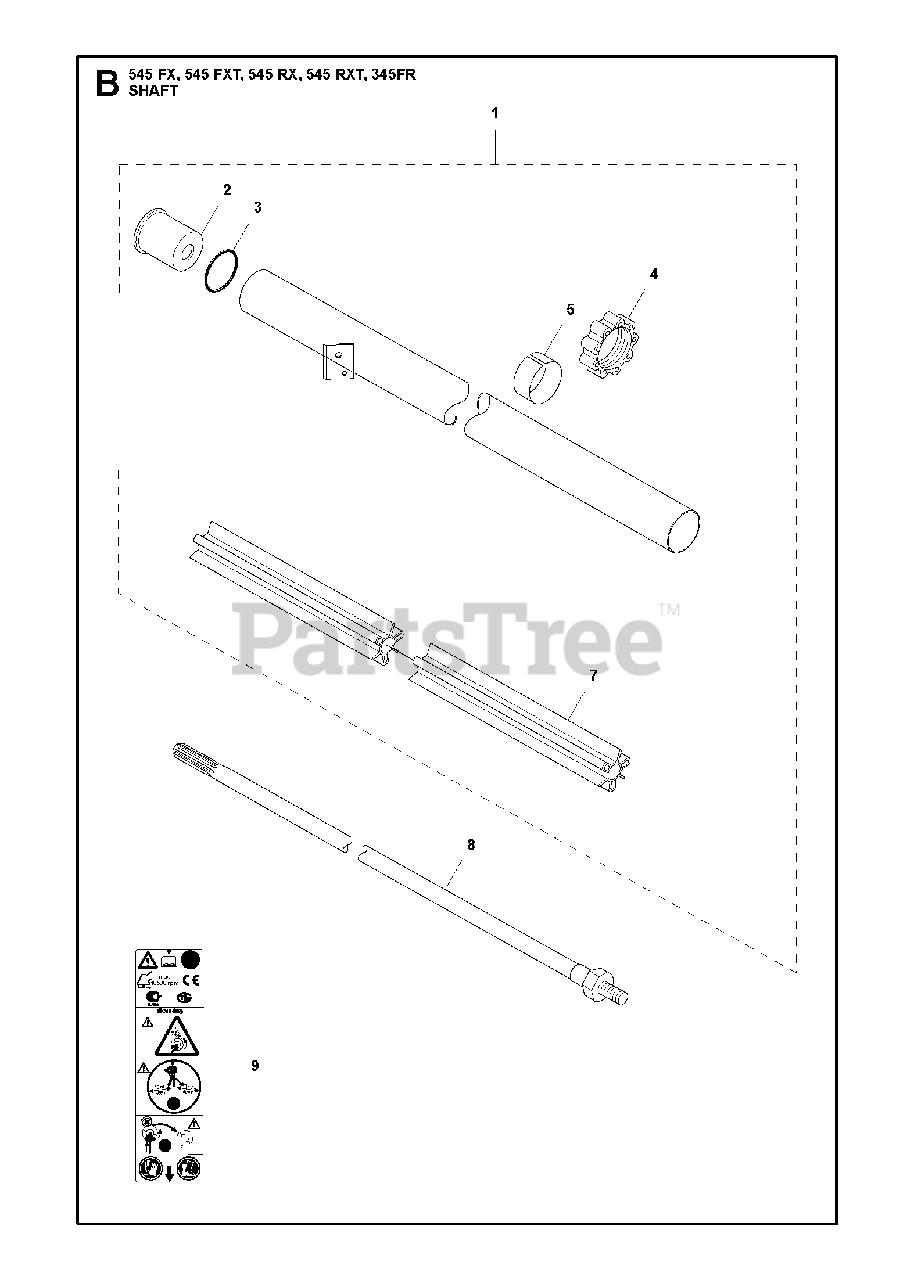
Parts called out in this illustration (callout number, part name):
1	TUBE ASSY
2	SPACER SLEEVE
3	O-RING
4	MOVEMENT LIMITER
5	BAND
7	BEARING SHAFT
8	SHAFT
9	LABEL WARNING TRIMMERS AND BRU
